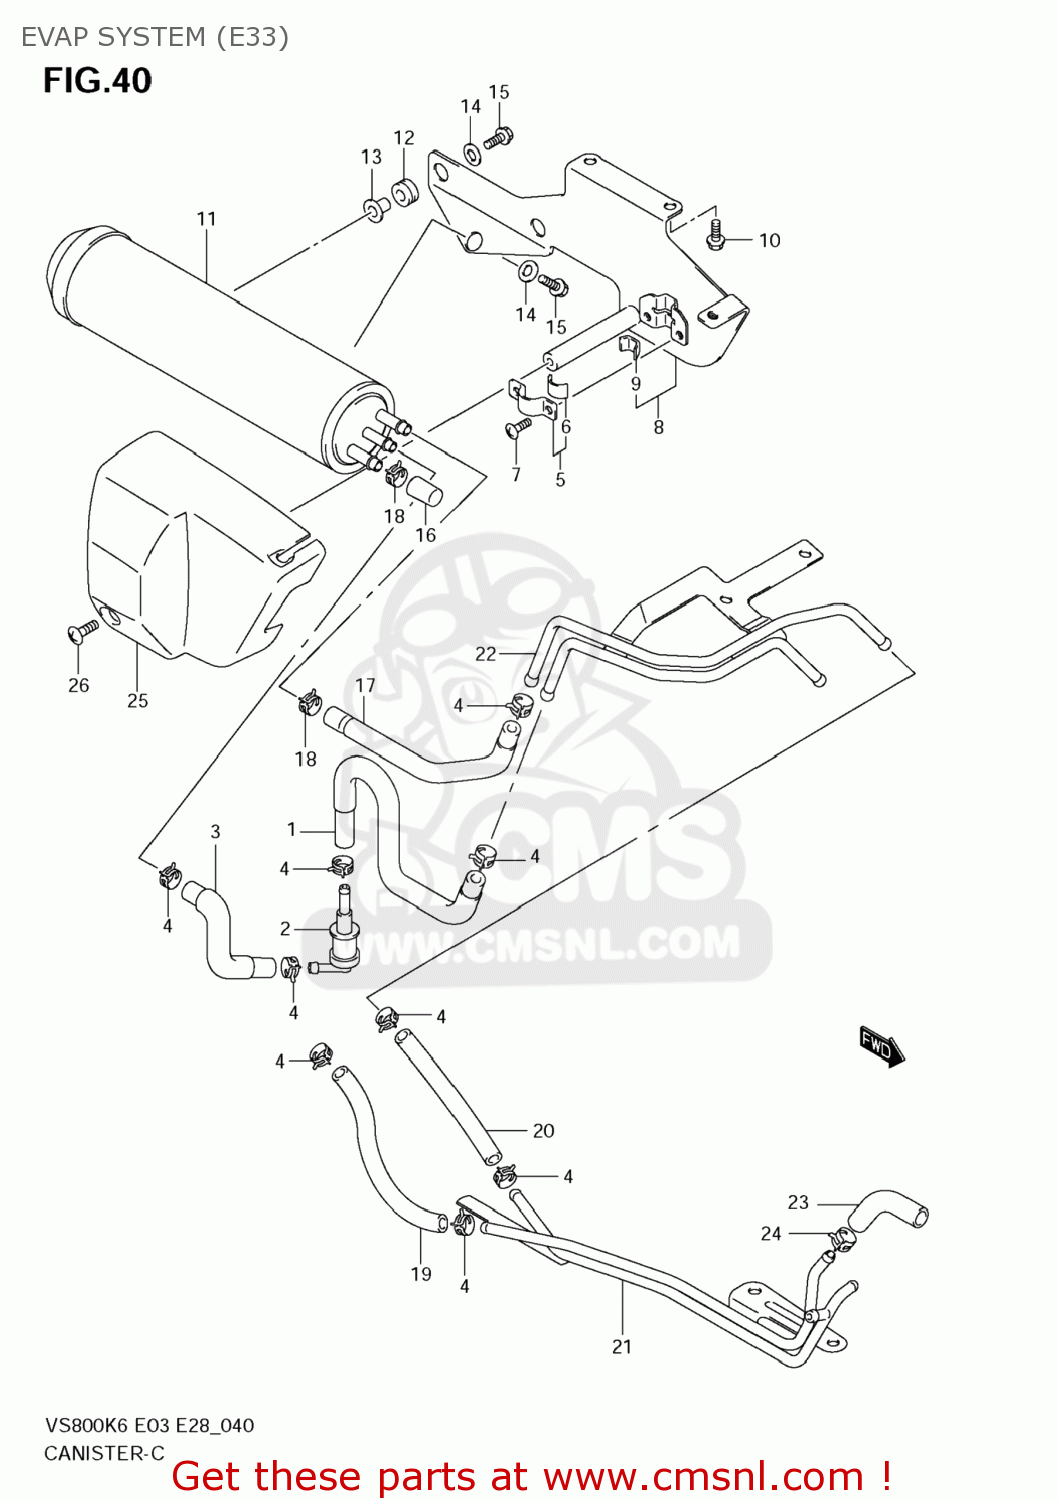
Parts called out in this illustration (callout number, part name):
1	HOSE,TANK & BREATHER VALVE
2	VALVE,FUEL TANK BREATHER
3	HOSE,CSTR & BREATHER VALVE
4	CLIP
5	PLATE,FUEL TANK BREATHER NO.2
6	CUSHION
7	SCREW
8	BRACKET,CANISTER
9	CUSHION
10	BOLT
11	CANISTER SET
12	CUSHION
13	WASHER
14	WASHER(6.5X16X3.2)
15	BOLT
16	CAP,OD:11.5
17	HOSE,CSTR PURGE
18	CLIP
19	HOSE,EVAP SYSTEM SURGE
20	HOSE,EVAP SYSTEM PURGE
21	PIPE,CSTR JOINT FR
22	PIPE,CSTR JOINT RR
23	HOSE,EVAP CHARGE
24	CLIP
25	COVER,BREATHER VALVE
26	SCREW(5X13)
